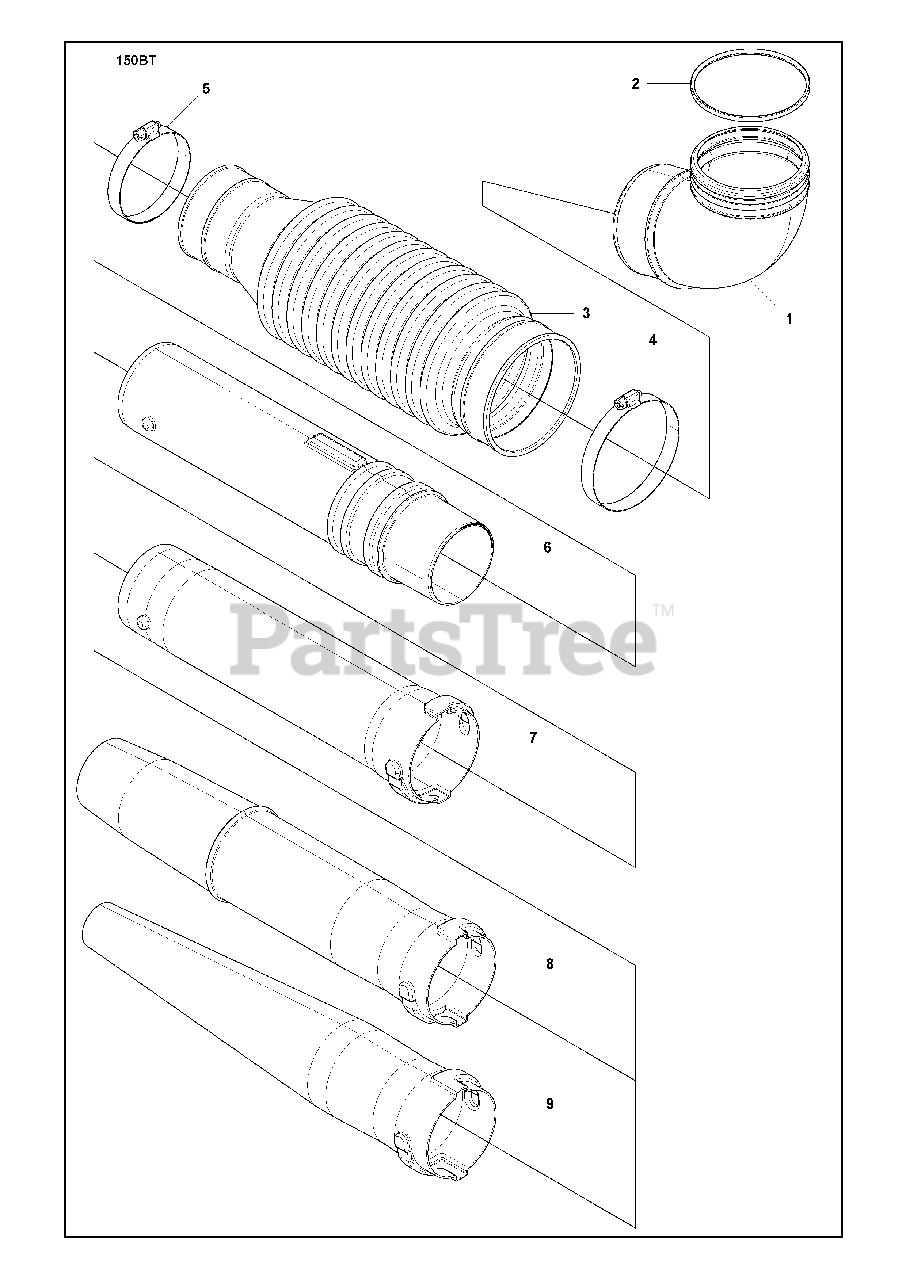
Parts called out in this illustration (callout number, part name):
1	PIPE BEND
2	O-RING
3	BELLOWS
4	CLAMP(F115)
6	SWIVEL JOINT
7	PIPE STRAIGHT
8	PIPE, END (RPLS 275651220)
9	PIPE CONCENTRAT0R 150BT
